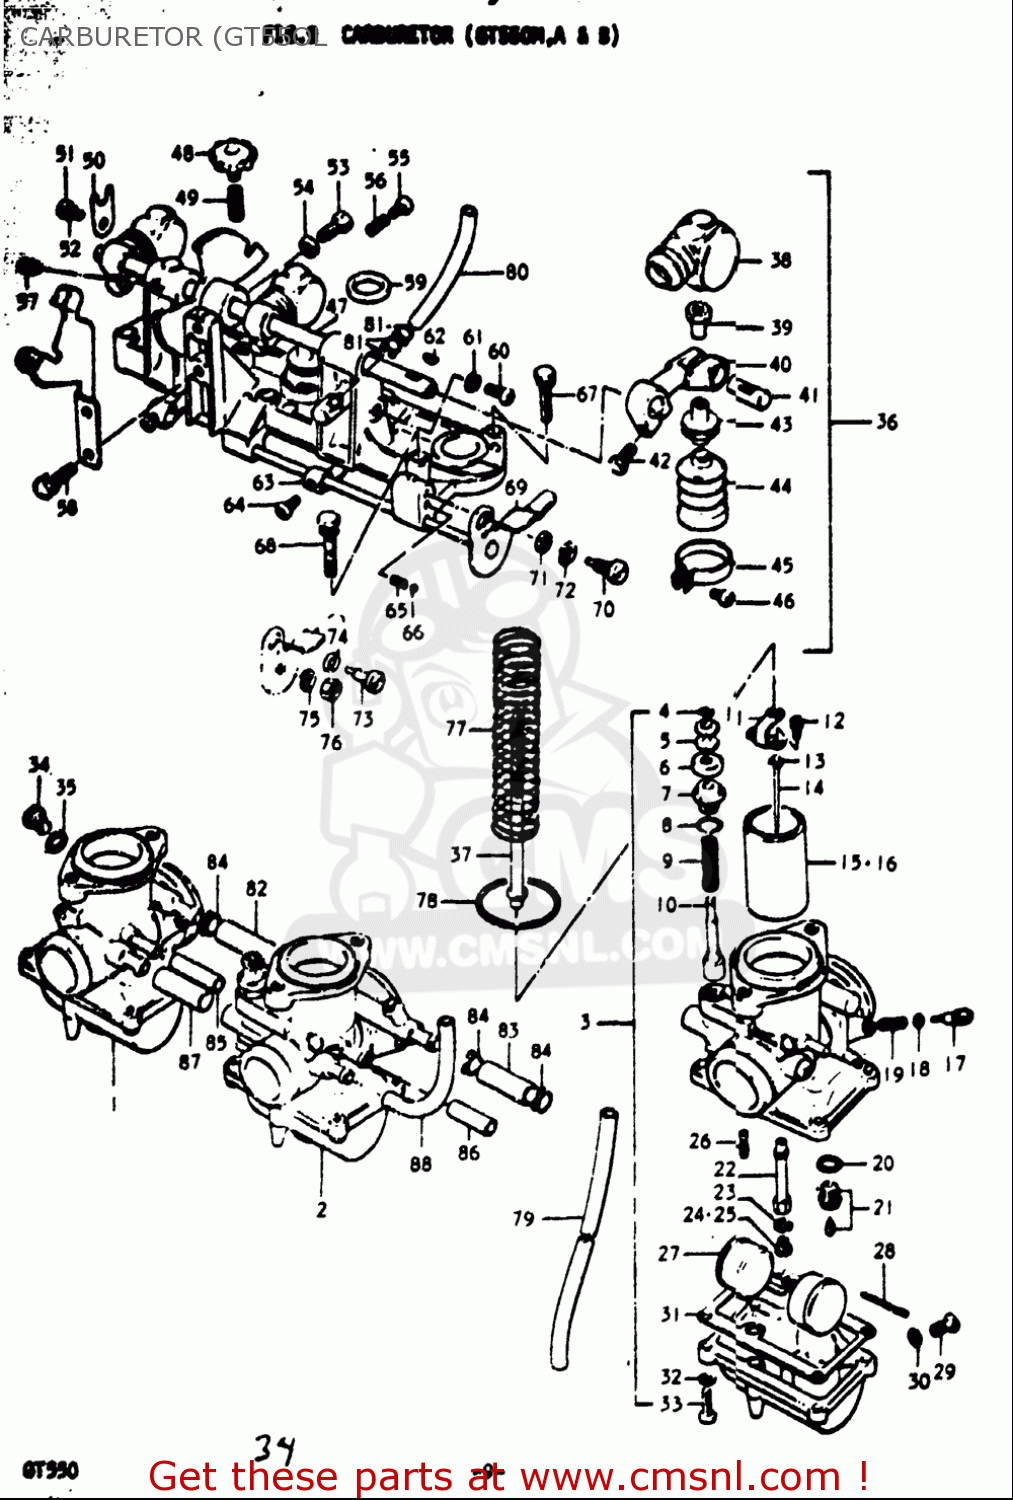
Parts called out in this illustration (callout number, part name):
4	CLIP,CARBURETOR STARTER
5	RING
6	CAP,PLUNGER
8	O RING(D:1.5,ID:8.5)
9	SPRING
12	SCREW
13	CLIP
17	SCREW,PILOT AIR ADJUSTING
18	O RING
19	SPRING
20	GASKET,VALVE SEAT (NAS)
21	VALVE ASSY,NEEDLE
23	WASHER
24	JET,MAIN(97.5)
25	JET,MAIN(95)
26	JET,PILOT(25)
27	FLOAT
28	PIN,FLOAT
29	PLUG
30	GASKET,DRAIN,PLUG (NAS)
31	GASKET,FLOAT CAHMBER (NAS)
32	WASHER,LOCK
33	SCREW 4X16
34	BOLT
35	GASKET,THRO VALVE INSPECTION (NAS)
38	CAP,RUBBER
40	ARM
44	BOOT, THROTTLE VALVE
46	SCREW
51	SCREW
52	WASHER,LOCK
53	SCREW(6X12)
56	SPRING,THROTTLE SCREW
57	NIPPLE
60	SCREW
61	SCREW(6X12)
64	SCREW
66	BALL,STARTER SHAFT
74	WASHER
78	O RING
79	HOSE,AIR BENT
80	HOSE(4.5X8.5X600)
81	CLIP
84	CLIP
87	HOSE,AIR BENT
88	HOSE(4.5X8.5X600)
